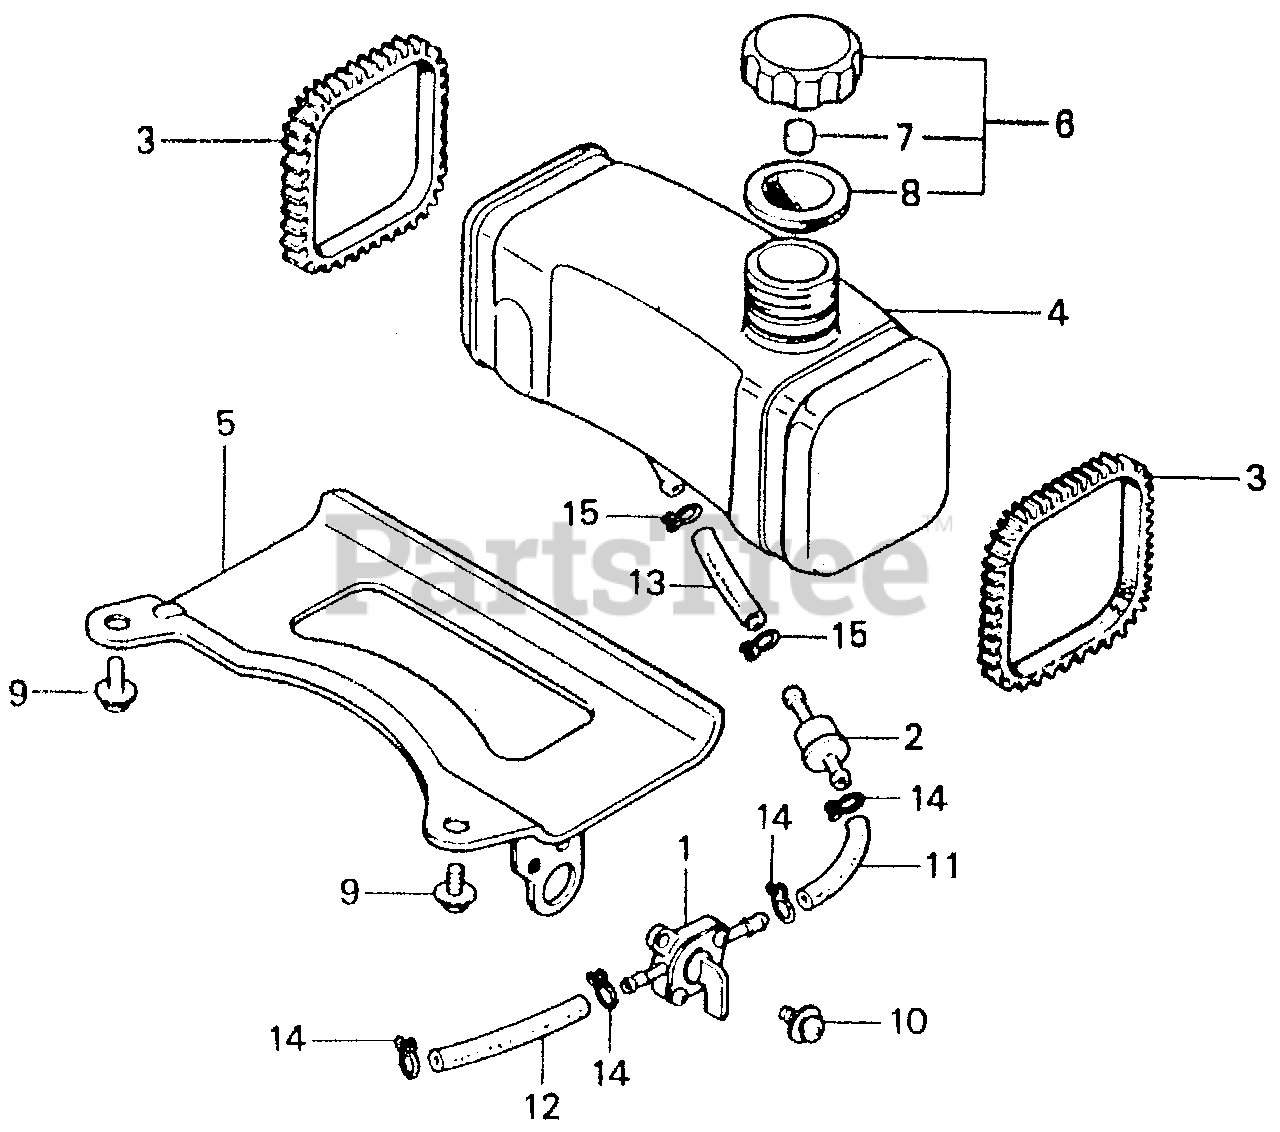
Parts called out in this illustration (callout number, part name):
1	PETCOCK ASSY.
2	FILTER, FUEL
3	CUSHION, TANK
4	TANK, FUEL
5	PLATE, TANK
6	CAP, FUEL TANK
7	SPONGE, FUEL CAP BREATHER
8	GASKET, FUEL CAP
9	SCREW-WASHER (5X10)
10	SCREW-WASHER (5X12)
11	BULK HOSE, FUEL (4.5X3000) (4.5X55)
12	BULK HOSE, FUEL (4.5X3000) (4.5X120)
13	BULK HOSE, FUEL (5.5X3000) (5.5X50)
14	CLIP, TUBE (B8)
15	CLIP, TUBE (B10)
